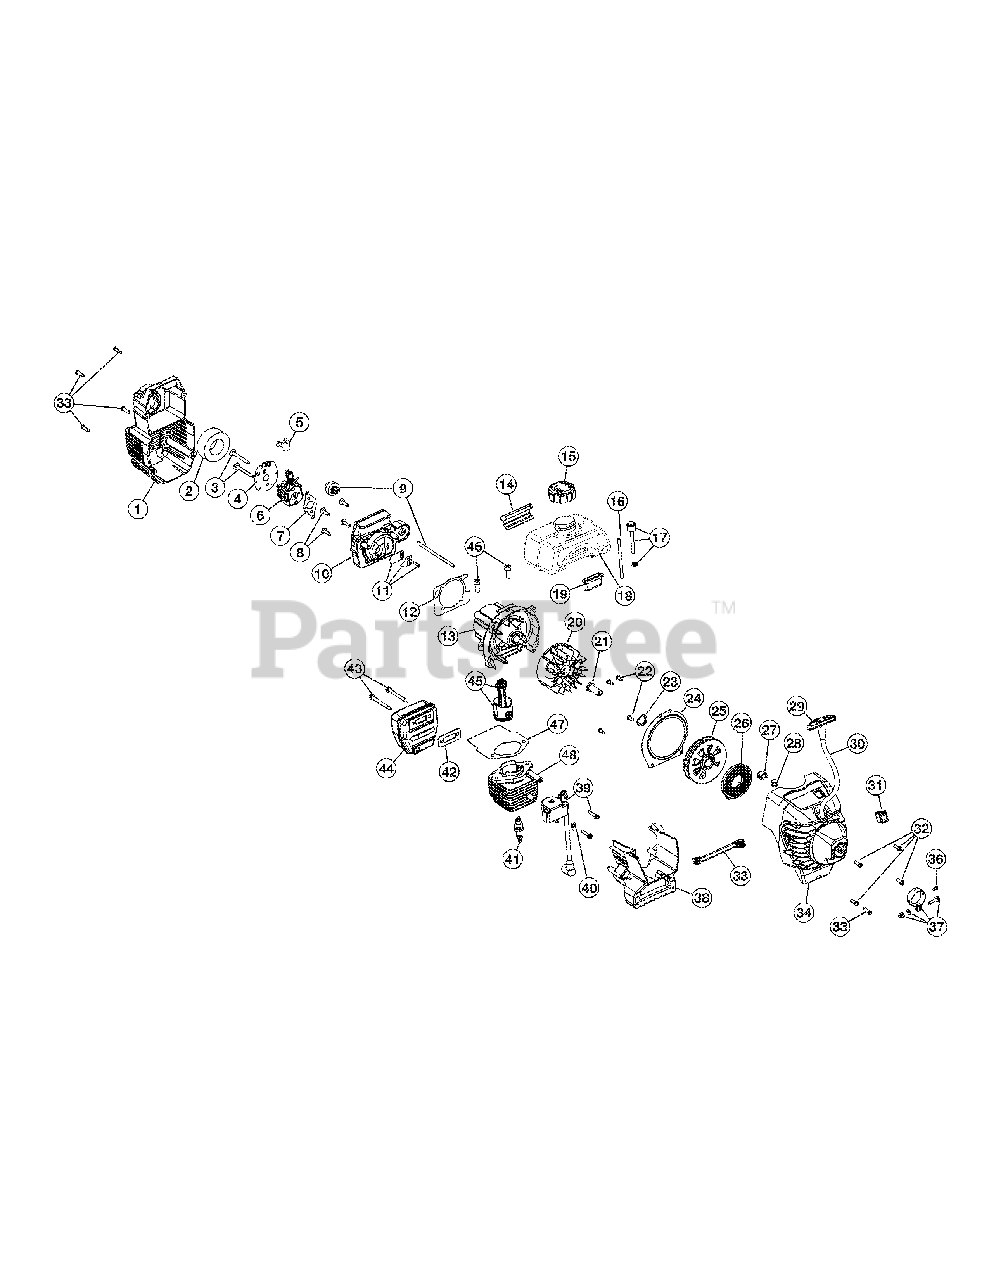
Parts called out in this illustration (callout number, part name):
1	Air Cleaner Cover Assembly (includes 2 & 33)
2	Air Cleaner Filter
3	Carburetor Mounting Screws
4	Choke Plate
5	Choke Lever
6	Carburetor Assembly (includes 7 & 17)
7	Carburetor Gasket
8	Carb Mount Screw
9	Primer and Hose Assembly
10	Carburetor Mount Assembly (includes 8, 11 & 12)
11	Reed Assembly
12	Carburetor Mount Gasket
13	Crankcase Service Assembly (includes 8)
14	Rear Mounting Pad
15	Fuel Cap Assembly
16	Fuel Return Line
17	Fuel Line Assembly
18	Fuel Tank Assembly (includes 15-17)
19	Front Mounting Pad
20	Flywheel Assembly
21	Square Nut Drive
22	Plate Screw
23	Palnut
24	Pressure Plate (includes 22 & 27)
25	Recoil Pulley Assembly (includes 23)
26	Recoil Spring
27	Eyelet Retainer
28	Rope Guide
29	Pull Handle
31	Switch Assembly
32	Housing Screw
33	Cover Screw
33	Wire Lead
34	Starter Housing Assembly (includes 22-34)
36	Anti-Rotation Screw
37	Clamp Assembly (includes 36)
38	Shroud Extension and Stand (includes 33)
39	Module Assembly
40	Ground Tab
41	Spark Plug
42	Exhaust Gasket
43	Muffler Mounting Bolt Assembly
44	Muffler Assembly (includes 42, 43 & Spark Arrestor )
45	Piston & Rod Assembly
46	Cylinder Bolt
47	Cylinder Gasket
48	Cylinder Assembly (includes 46 & 47)
